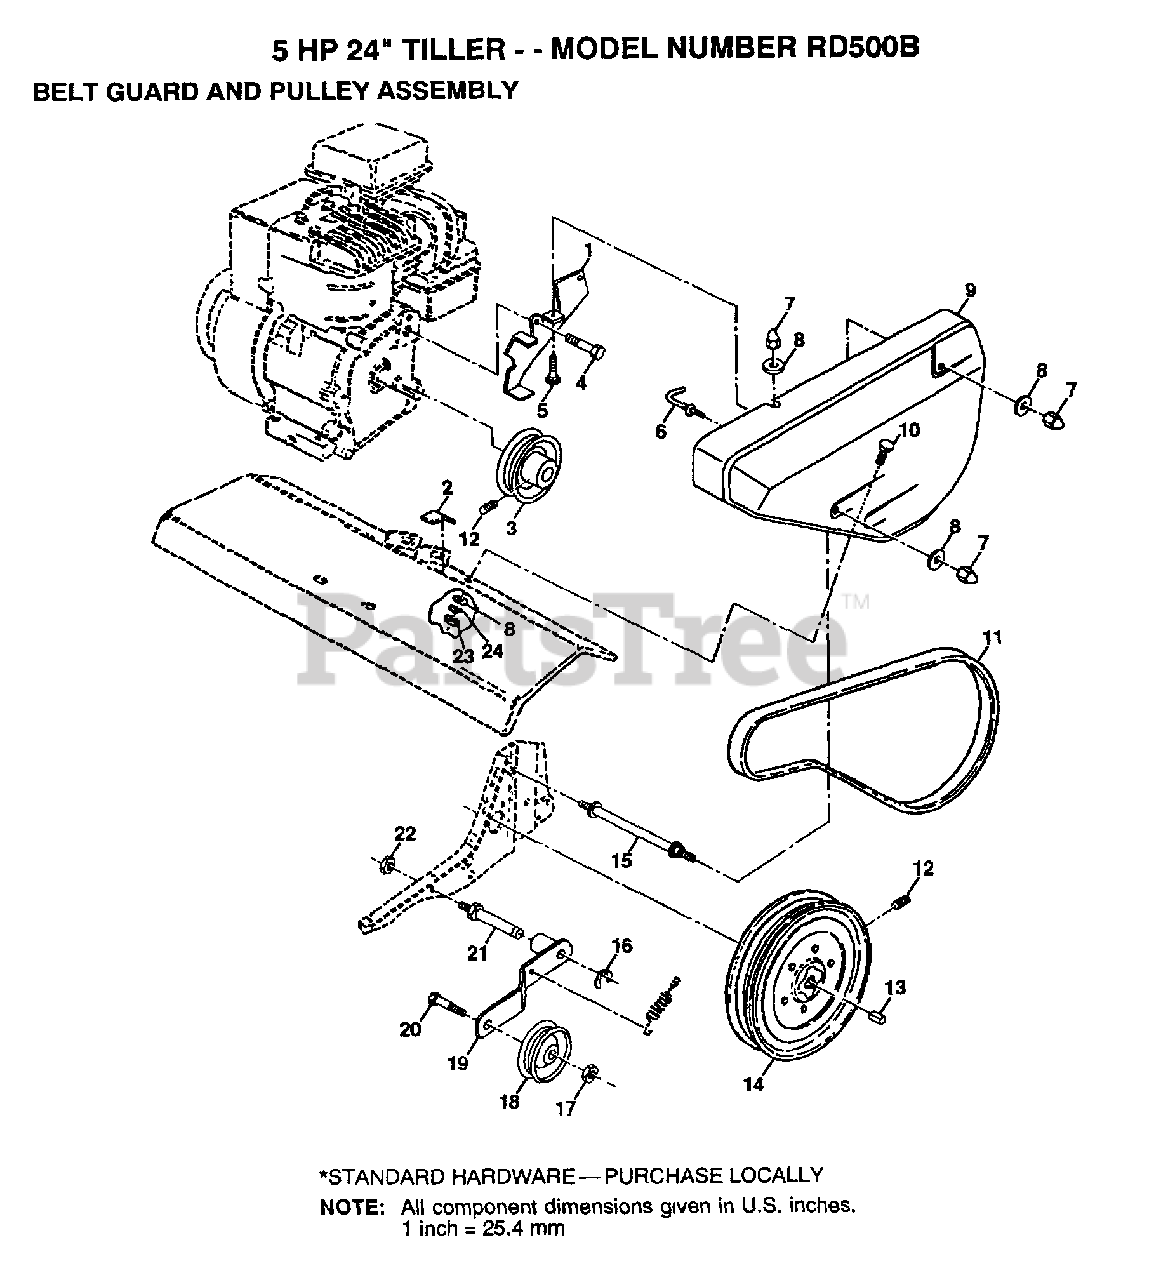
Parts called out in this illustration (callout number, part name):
2	PAD IDLER TI
3	ENGINE PULLEY
5	BOLT
7	NUT-CAP TI
8	WASHER
10	BOLT T
11	V BELT STD
12	SET SCREW
13	KEY T
14	TRANS SHEAVE RT
15	BOLT TI
16	KLIP RING TI
17	NUT
19	IDLER ARM TI
21	SHAFT IDLER TI
22	JAM NUT TI
24	LOCKWASHER
